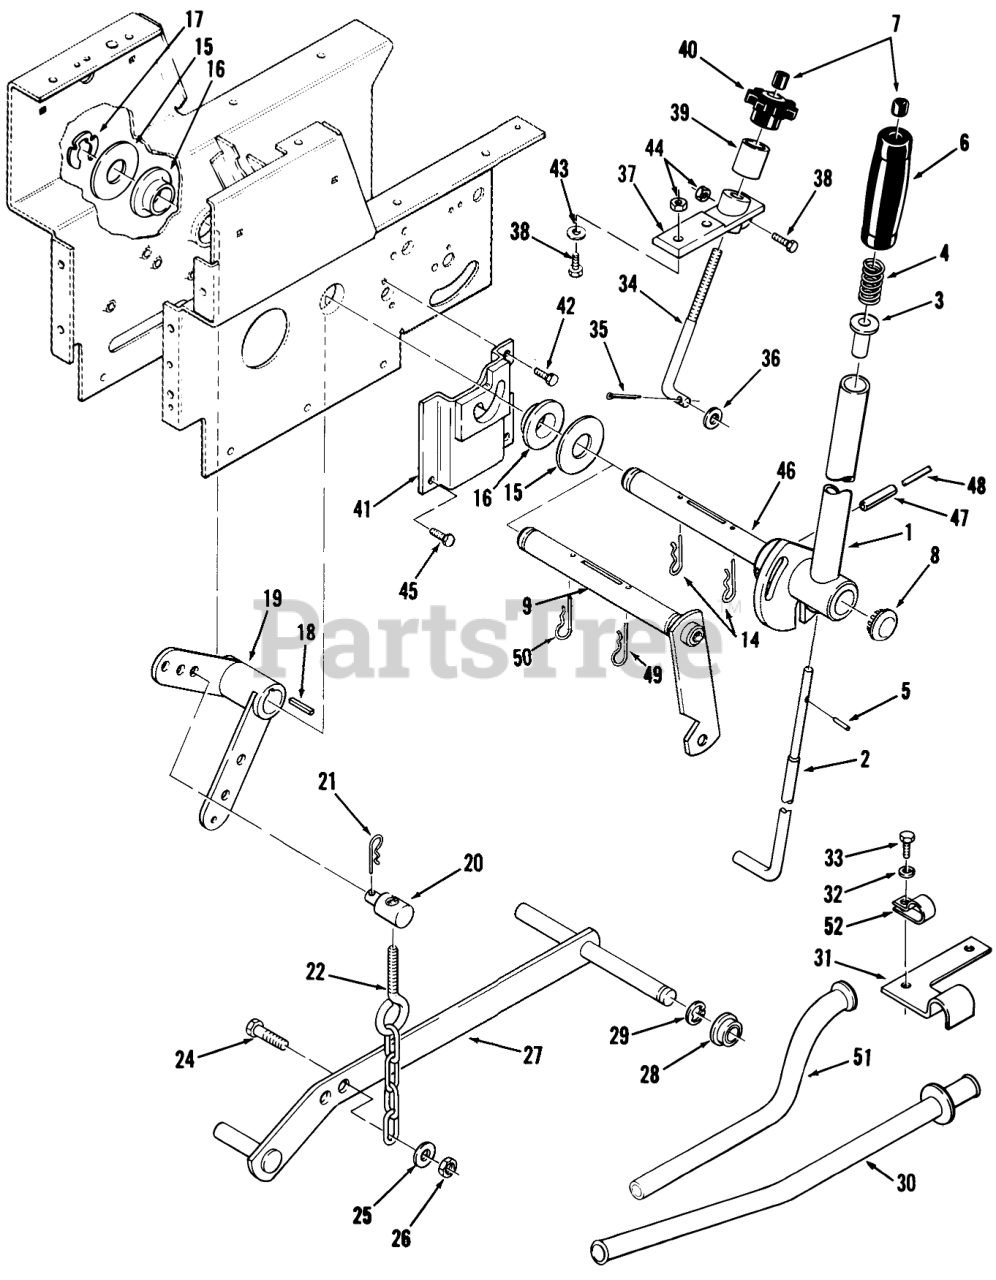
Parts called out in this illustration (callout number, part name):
1	Lift Lever (Includes Items 46, 47, 48)
2	ROD-LATCH LIFT
3	RETAINER-SPRING
4	SPRING-COMPRESSION
5	PIN-SPIROL
6	HANDGRIP
7	CAP-ROD, PLUNGER
8	PLUG
9	Lift lever
14	Pin-Cotter
15	WASHER
16	BEARING-FLANGE
17	Retainer
18	KEY-SQUARE
19	Bellcrank
20	TRUNNION
21	Hairpin
22	CHAIN-LIFT
24	Bolt
25	WASHER 5/16 SAE
26	Nut
27	ASSY LIFT BAR R
28	BUSHING
29	E Ring
30	TUBE ASSY COMPLET R
31	CLAMP-CONDUIT R
32	LOCKWASHER
33	Bolt
34	Rod
35	Pop Rivet
36	WASHER -4
37	Casting
38	Bolt
39	Sleeve
40	KNOB-LIFT CONTROL
41	Latch Bracket
42	SCREW
43	WASHER 5/16 SAE
44	Nut
45	Bolt
46	SHAFT-LIFT LEVER
47	SPIROL PIN
48	Roll Pin
49	Hairpin
50	Pin-Cotter
51	TUBE-CONDUIT R
52	CLIP
